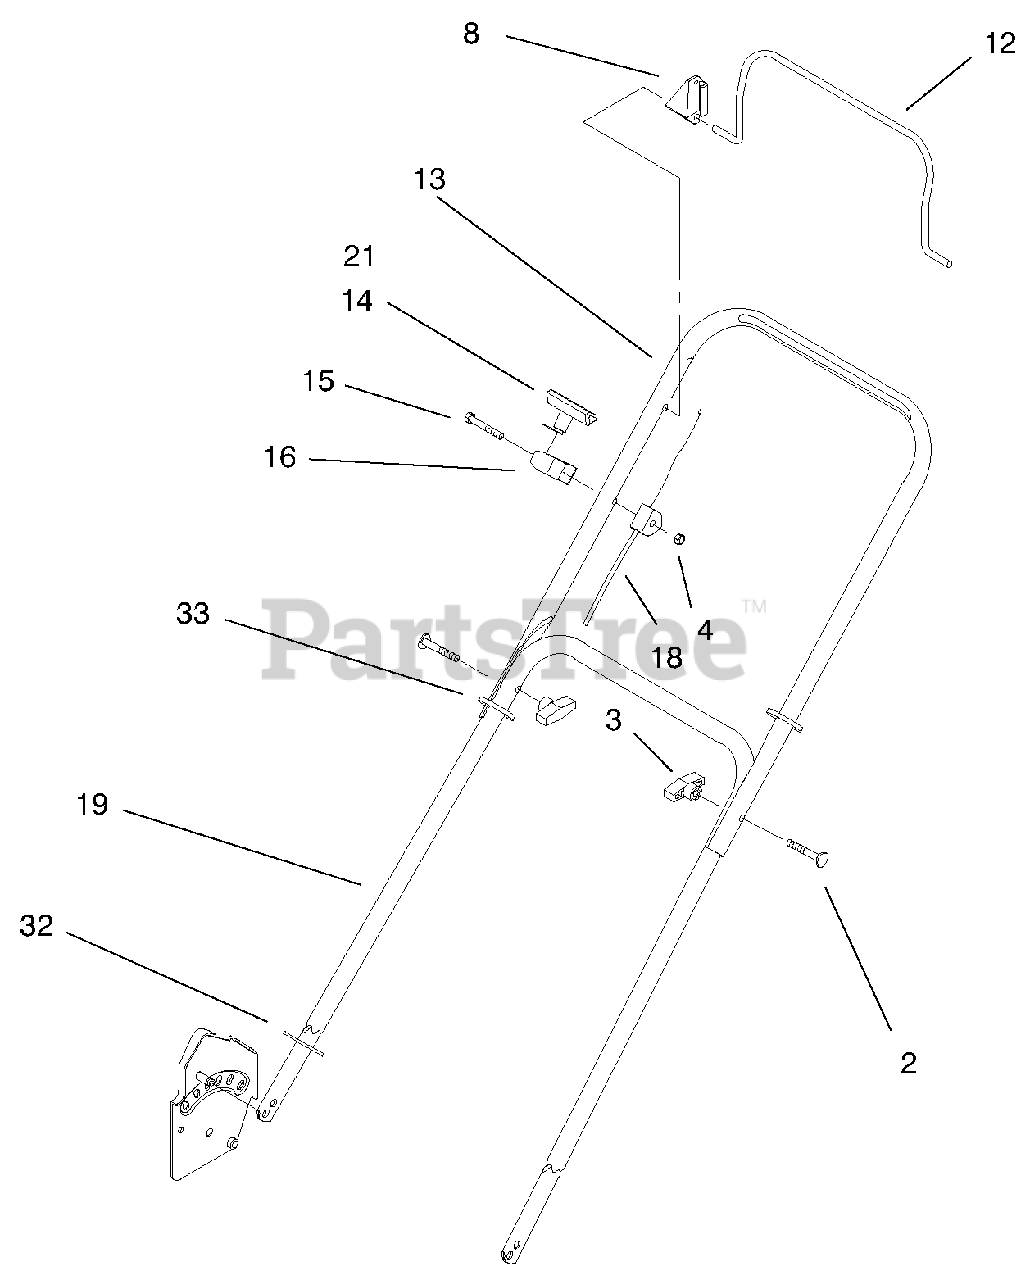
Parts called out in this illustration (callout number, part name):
2	Screw-Handle
4	Nut-Lock
8	Stop-Pivot
12	Bail-Flywheel Brake
13	Handle Section-Upper
14	Handle-Starter
16	Guide-Rope
18	ASM-Brake Cable
19	Handle Section-Lower
21	Staple-Handle
32	Handle-Guard
33	Tie Strap
